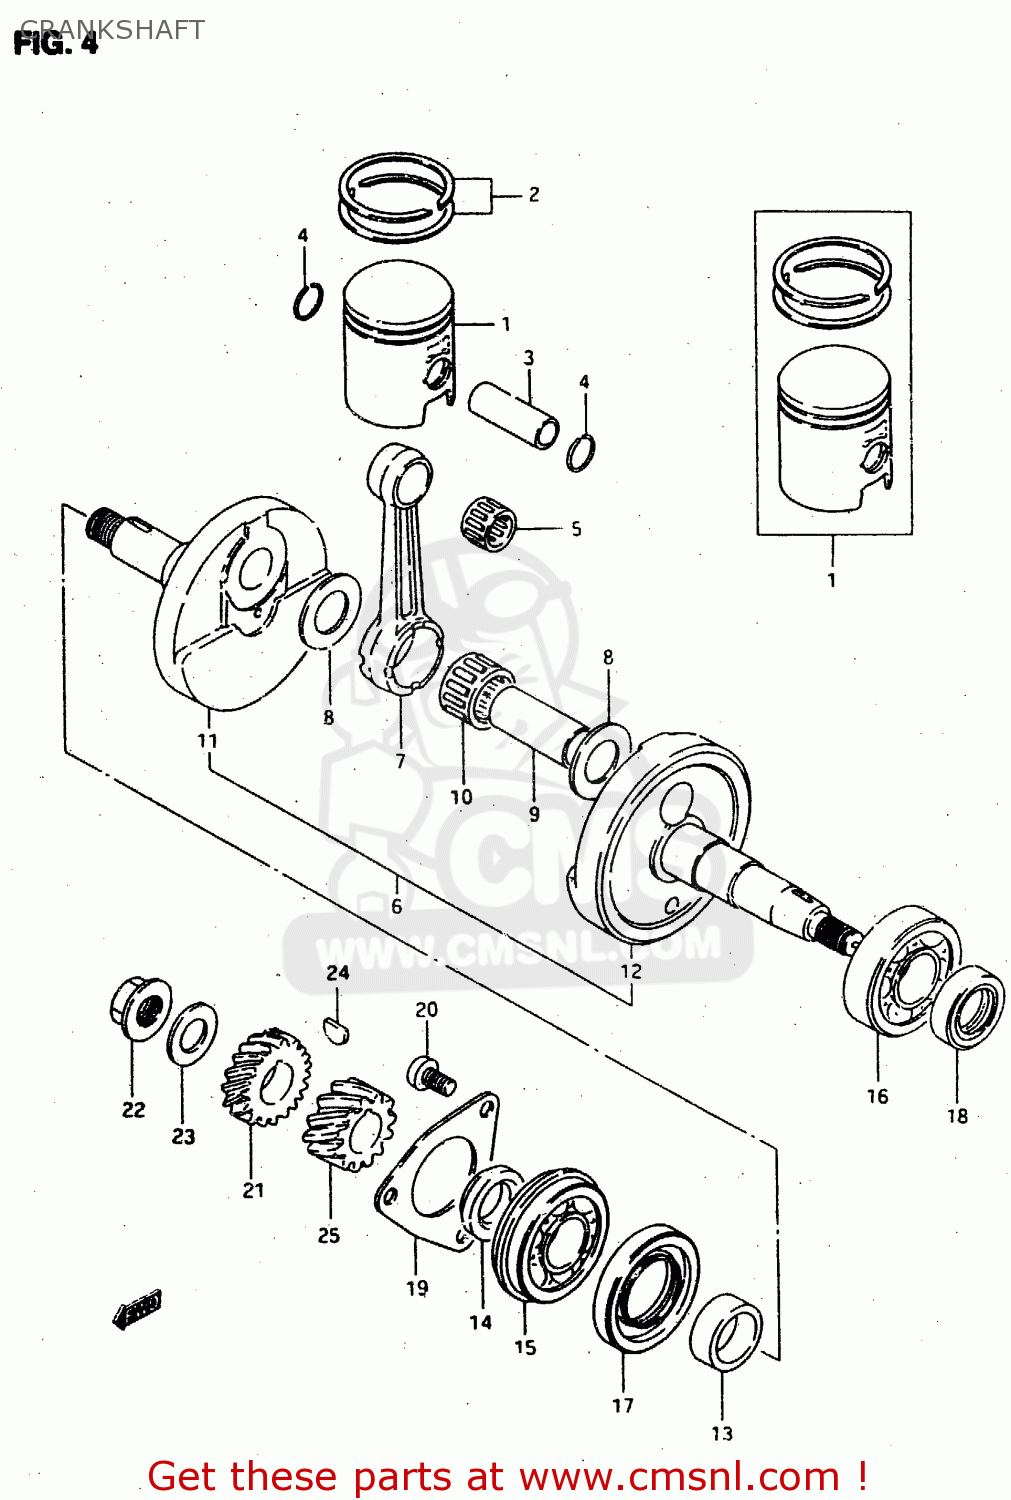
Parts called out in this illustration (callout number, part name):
1	PISTON
2	RING SET,PISTON
3	PIN,PISTON
4	RING,SNAP
5	ROLLER BEARING (12X16X1
6	CRANKSHAFT
7	ROD,CONNECTING
8	WASHER(16X29X1)
9	PIN,CRANK
10	BEARING 16X22X12
11	CRANKSHAFT, RH
12	CRANKSHAFT,LH
13	SPACER(20X28X10)
14	SPACER(16X27X7)
15	BEARING(20X47X14)
16	BEARING(20X47X14)
17	SEAL,OIL(28X47X7.3)
18	SEAL,OIL(18X30X8)
19	RETAINER
20	SCREW
21	GEAR,PRIMARY DRIVE
22	NUT
23	WASHER
24	KEY
25	GEAR,TACHOMETER DRIVE
